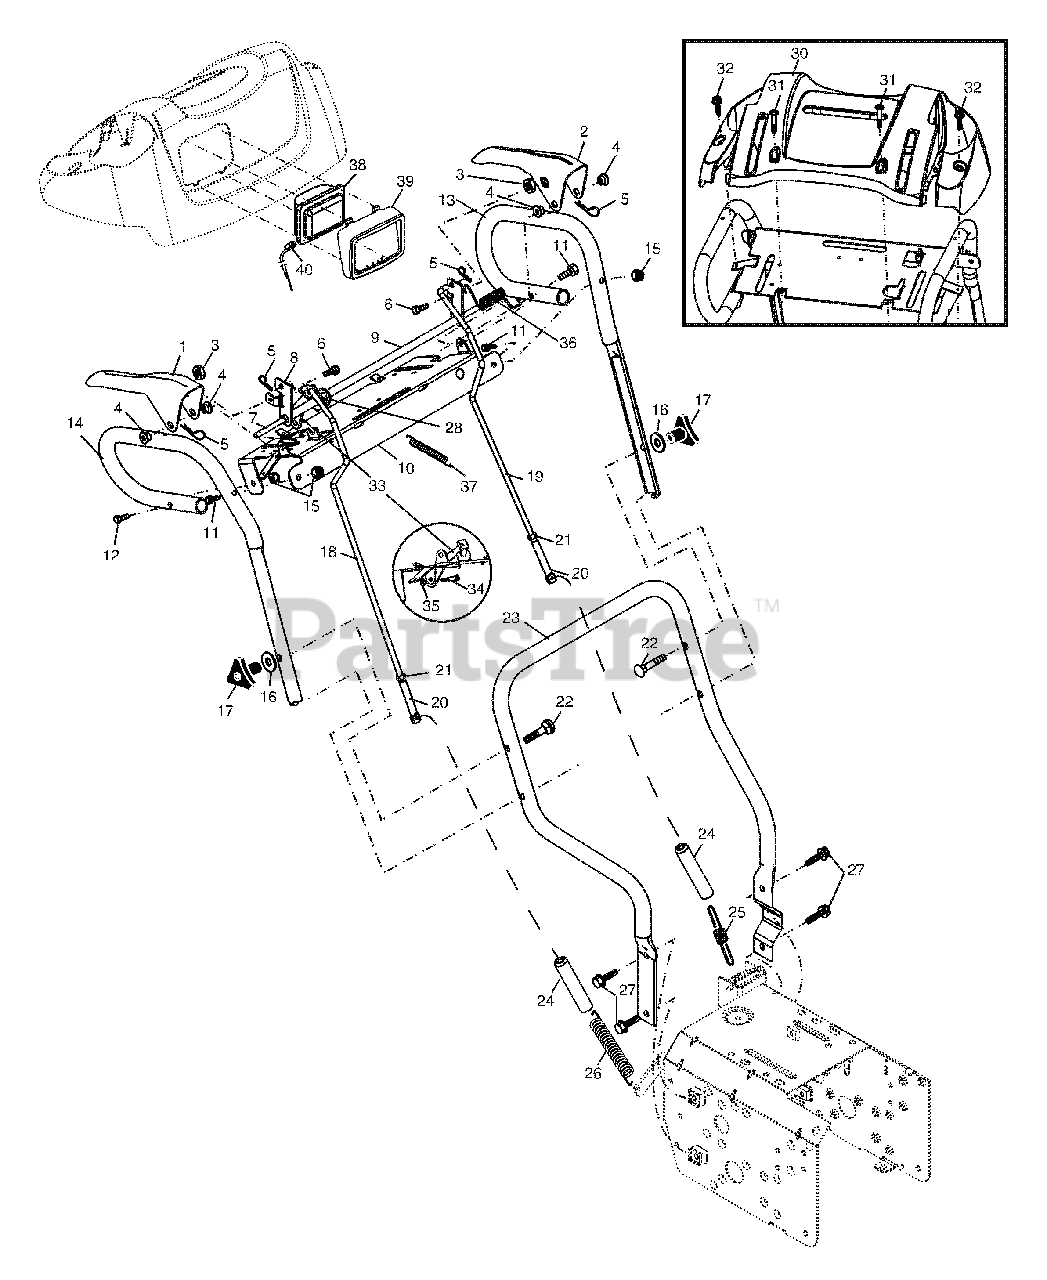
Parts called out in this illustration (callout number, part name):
1	Lever, Auger Control, RH
2	Lever, Traction Drive Control, LH
3	Nut, Cage 1/4-20
4	Bushing, Flange
5	Retainer, Hairpin
6	Screw, Hex Head 1/4-20 x 3/4
7	Rod, Interlock
8	Tube Assembly, Interlock, RH
9	Tube Assembly, Interlock, LH
10	Panel, Control
11	Screw, Hex Head 5/16-18 x 1-1/2
12	Screw, Hex Head 5/16-18 x 1-3/4
13	Handle Tube, LH
14	Handle Tube, RH
15	Nut, Lock 5/16-18
16	Washer, Flat 3/8
17	Knob, Handle
18	Rod, Auger Control
19	Rod, Traction Control
20	End, Control Rod
21	Nut, Hex, Jam 5/16-18
22	Bolt, Carriage 3/8-16 x 2-1/4
23	Handle Tube, Lower
24	Sleeve, Spring
25	Spring, Traction Drive
26	Spring, Auger Control
27	Screw, Hex Head 3/8-16 x 1
28	Clip, Panel
30	Console, Panel
31	Screw, Hex Head, Tapping #10-24 x 1-1/4
32	Screw, Hex Head, Tapping #10-24 x 1/2
33	Latch, Interlock
34	Bolt, Shoulder
35	Nut, Lock 1/4-20
36	Spring, Torsion
37	Spring, Interlock
38	Headlight, Halogen
39	Bezel, Headlight
40	Harness, Headlight (Halogen)
